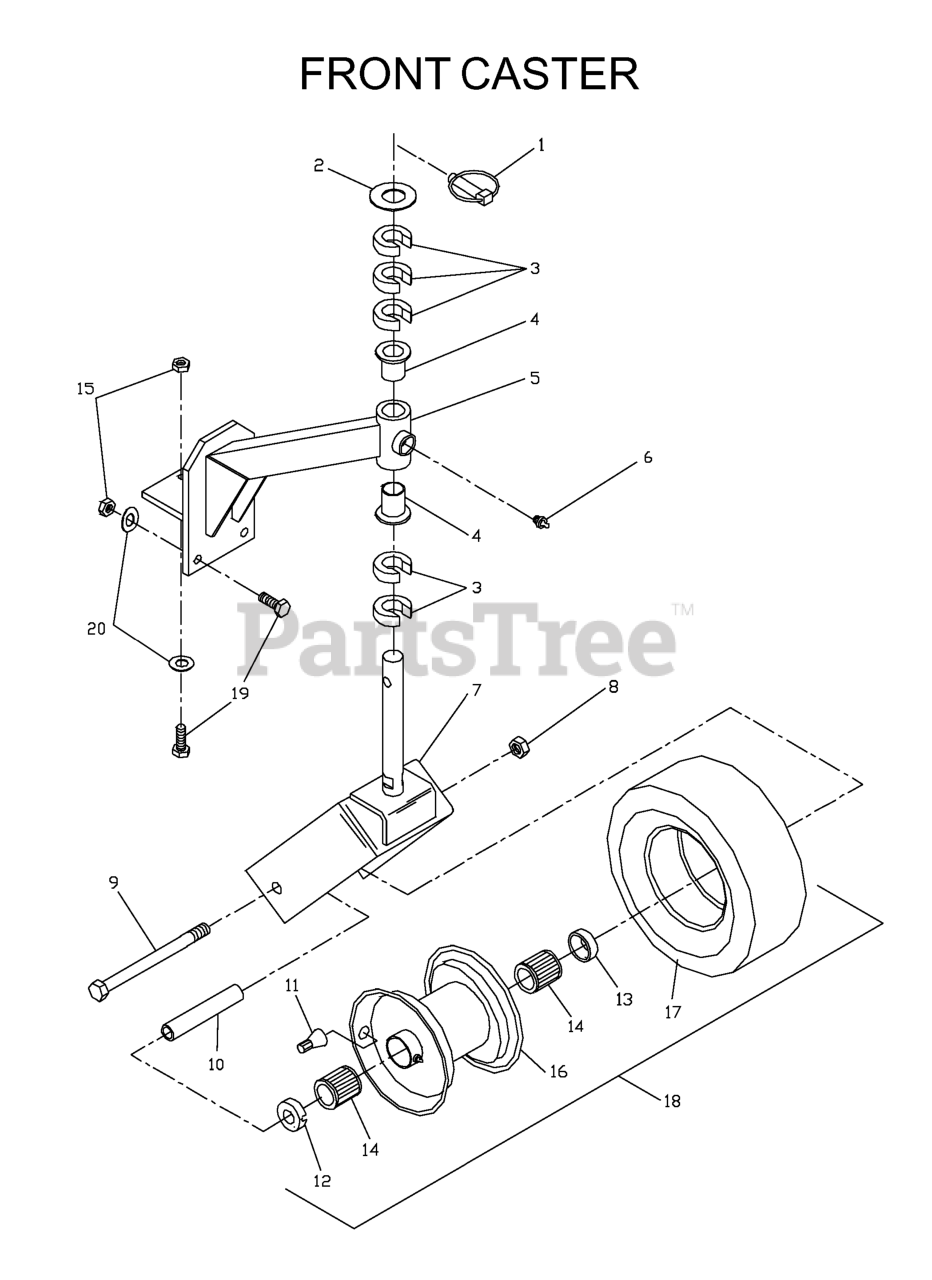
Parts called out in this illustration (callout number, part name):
1	LYNCH PIN 7/16
2	MACHINE BUSHING
4	BUSHING, FLANGED
5	CASTER ARM W/BUSHING
6	ZERK 1/8 NPT
7	CASTER YOKE
8	NUT 1/2-13 HEX NYLOC ZD
9	HCS 1/2C X 5 1/2
11	VALVE STEM TR-412
12	ENDCAP, NOTCHED
13	ENDCAP
14	ROLLER BEARING
15	NUT 3/8C CENTERBLOCK
17	TIRE 9 X 3.5 - 4
18	TIRE/WHEEL.CASTER.9X3.5-4.SMOO
19	HCS 3/8-16X1.GRD.5.ZD
20	WASHER 3/8 FLAT
21	WHEEL CAST. ASM KIT
